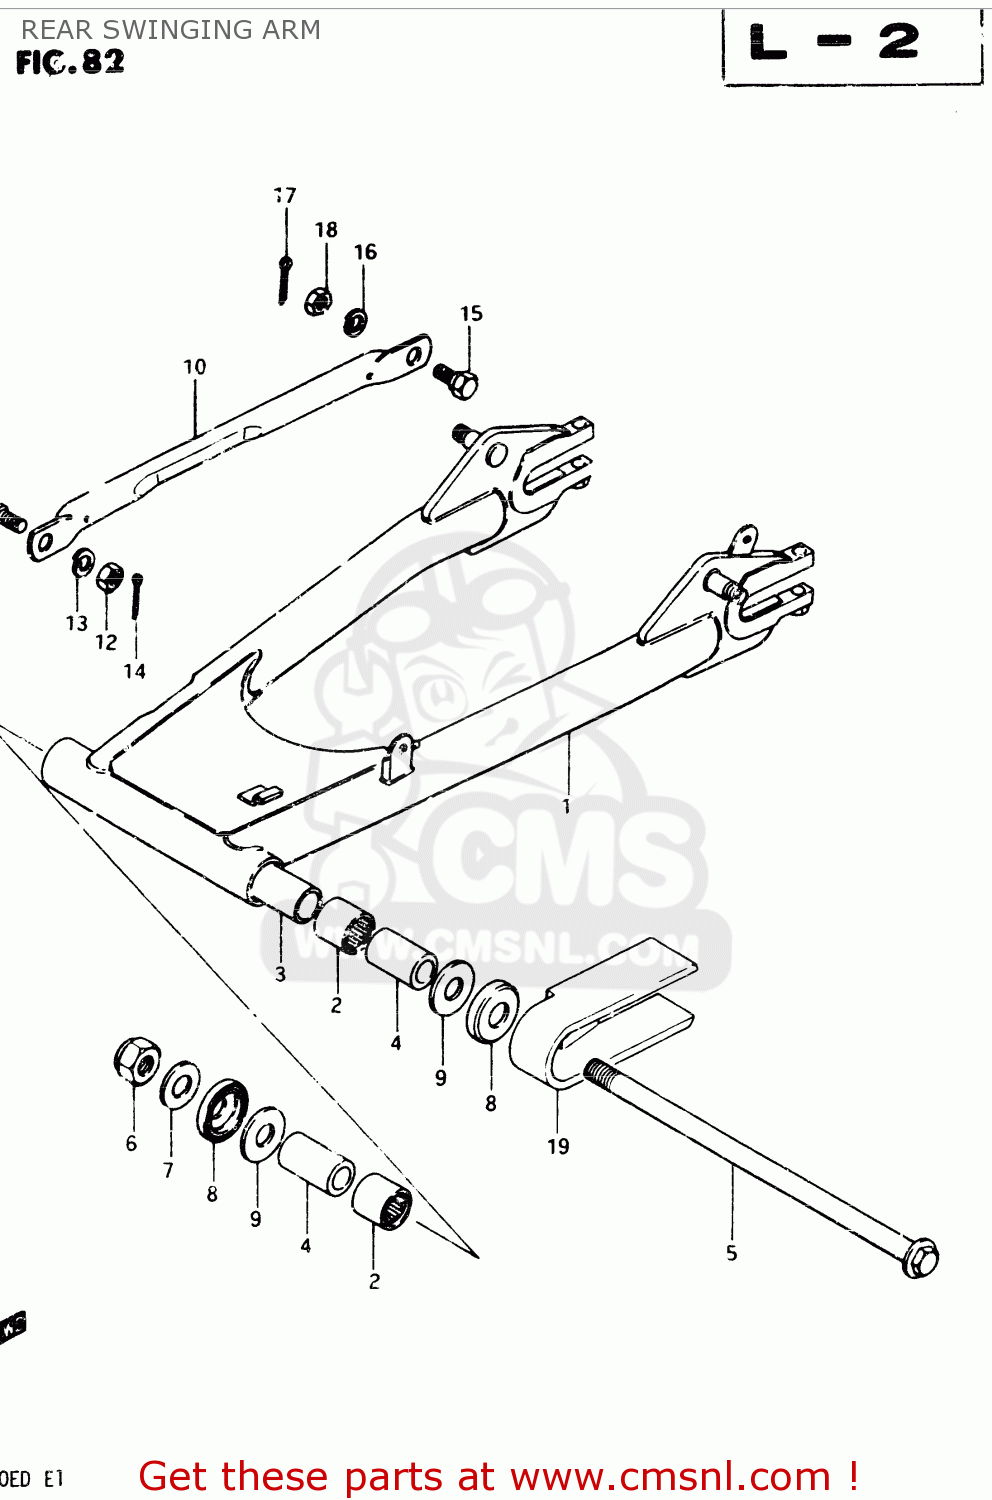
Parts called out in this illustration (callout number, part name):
1	ARM,REAR SWING
2	BEARING(22X29X30)
3	SPACER,SWINGINGARM CTR
4	SPACER,RR SWGARM PIVOT
5	SHAFT,REAR SWING ARM
6	NUT 14MM
7	WASHER
8	CVR,RR SWGARM DUST SEAL(OD:40)
9	WASHER(14.2X34X1)
10	TORQUE LINK,REAR
11	BOLT(10X24.5)
12	NUT
13	LOCK WASHER
14	PIN 20X20
15	BOLT(10X31)
16	LOCK WASHER
17	PIN 20X20
18	NUT
19	BUFFER,CHAIN TOUCH DEFLECTOR
